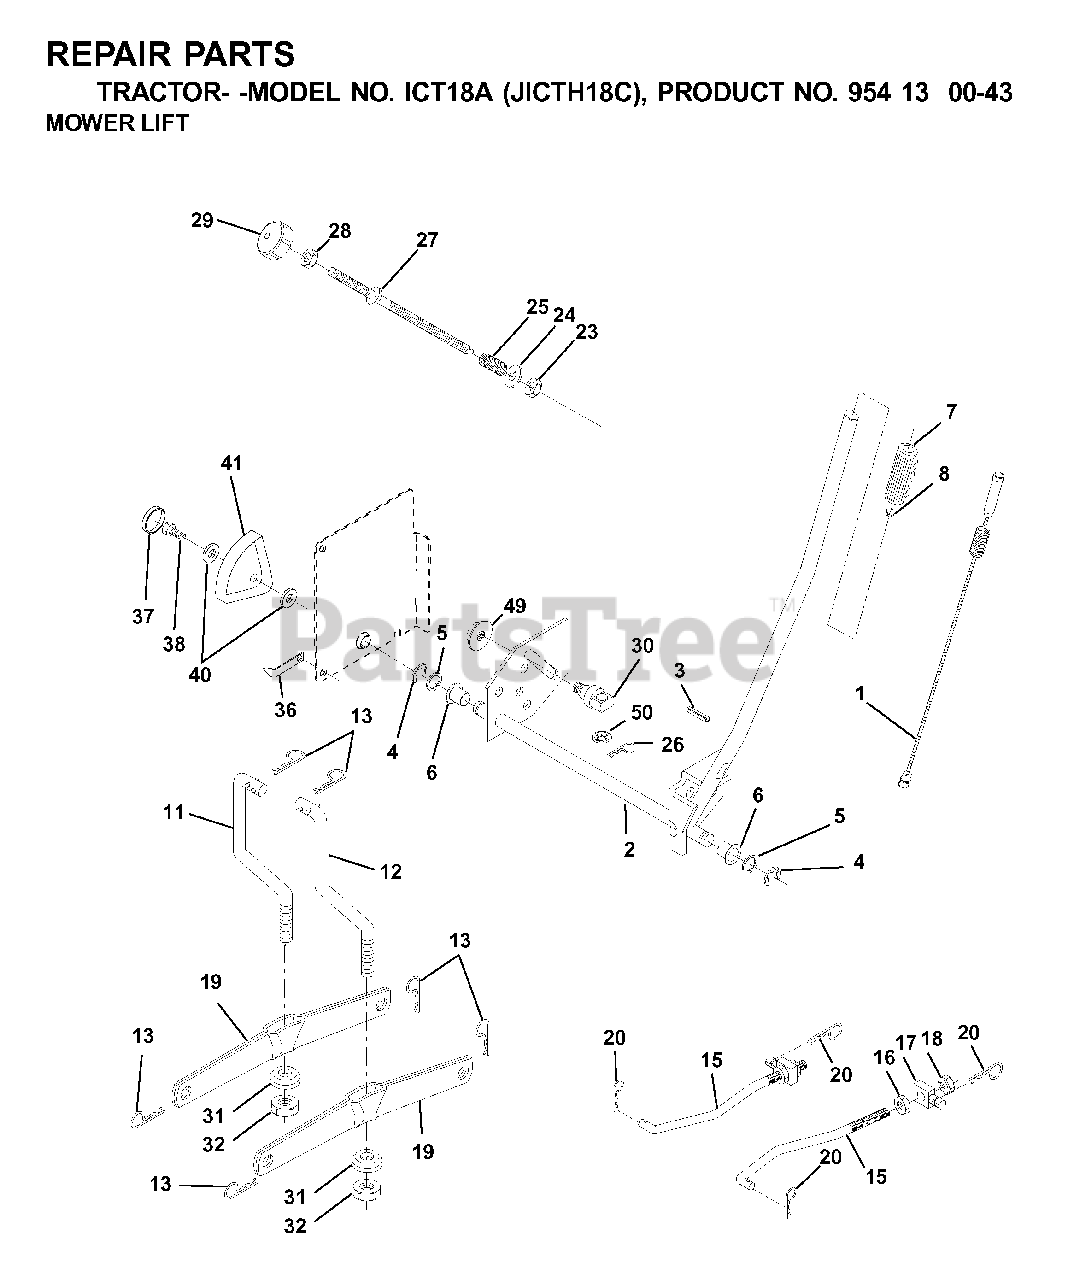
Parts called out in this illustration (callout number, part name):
1	WIRE ASM INNER W/ PLUNGER LT
2	SHAFT ASM R HANDLE
3	PIN GROOVE
4	RETAINING RING LT
6	BEARING.NYLON
7	GRIP HANDLE
8	PLUNGER BUT KIT
11	LINK
12	LINK
13	RETAINER-SPRNG RB
15	LINK.SUSPENSION.FRONT
16	NUT
17	TRUNION
18	NUT
19	ARM.REAR.SUSPENSION
20	SPRING RETAINER
25	SPRING**
26	RETAINER CLIP
27	ROD ADJ LIFT
28	NUT
29	KNOB INF 3/8-16
31	BEARING.PIVOT.LIFT
32	NUT CROWNLOCK 3/8-24
36	POINTER, HEIGHT INDICATOR
37	PLUG,HOLE
38	SCREW 5/16-18X1
41	HEIGHT INDICATOR
49	NUT
50	NUT PUSH M
